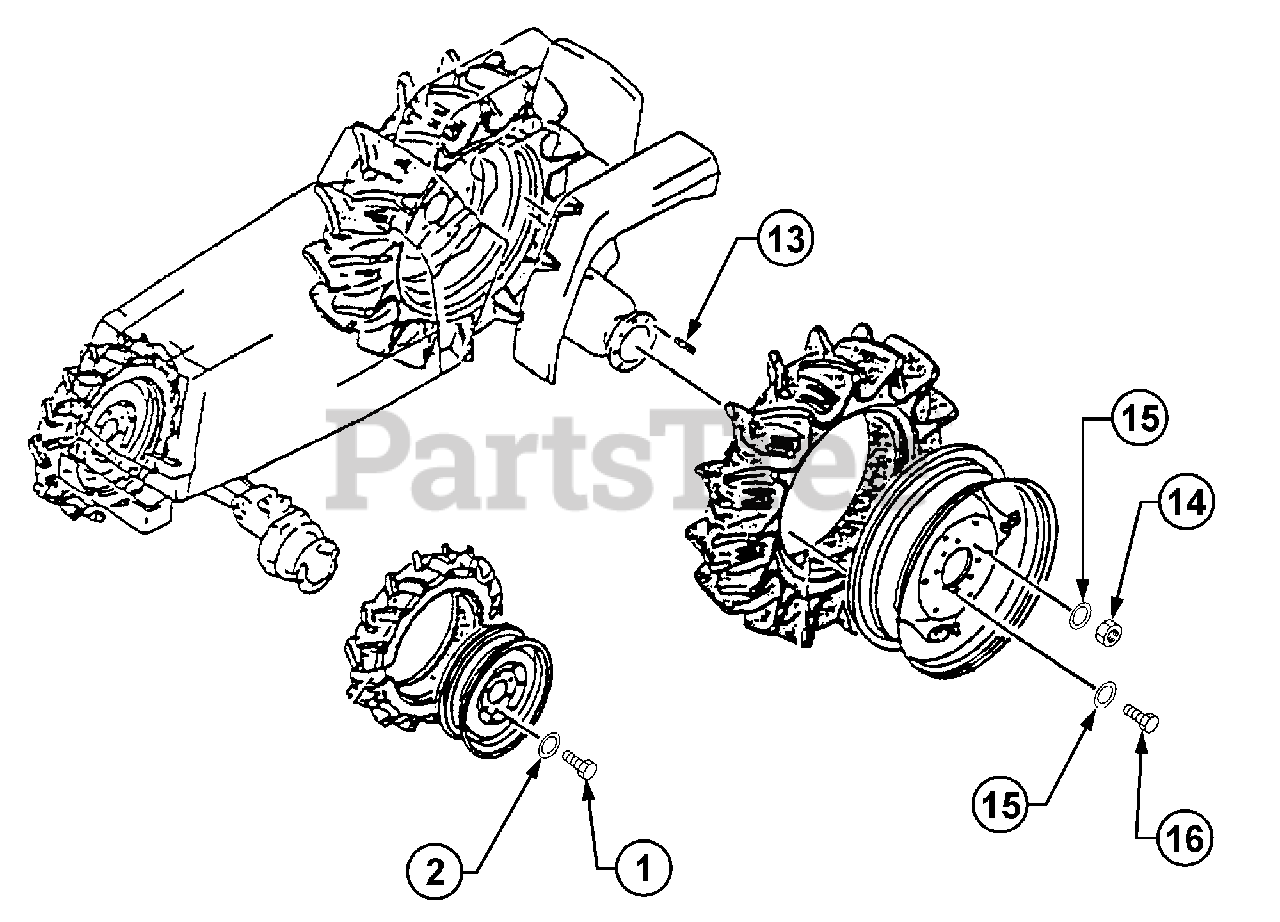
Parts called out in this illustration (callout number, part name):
1	Bolt
13	Bolt, Stud - Before S/N 21736
13	Bolt, Stud - S/N 21736 and After
14	Nut - Before S/N 21736
14	Nut - S/N 21736 and After
16	Bolt - Before S/N 21736
16	Bolt - S/N 21736 and After
